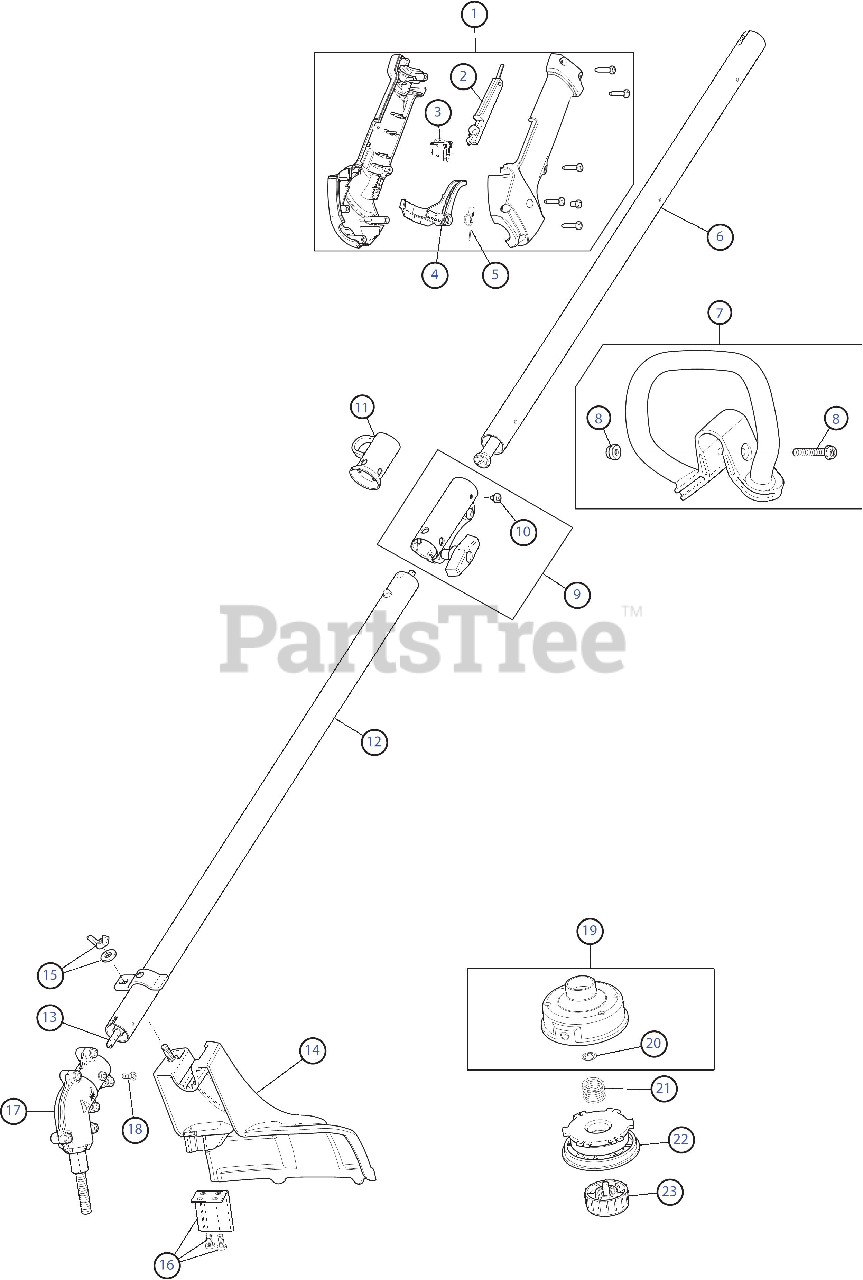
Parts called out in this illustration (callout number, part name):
1	Throttle Housing Assembly
2	Throttle Trigger Lock-Out
3	Trigger Switch Assembly
4	Throttle Trigger
5	Throttle Trigger Spring
6	Upper Drive Shaft Housing Assembly
7	D-Handle
8	D-Handle Hardware Assembly
9	Split Boom Coupler
10	Anti-Rotation Screw
11	Hanger
12	Lower Drive Shaft Housing Assembly
13	Lower Flexible Drive Shaft
14	Shield Assembly
15	Shield Mounting Hardware
16	Blade Assembly
17	Gear Box Assembly
18	Anti-Rotation Screw
19	Outer Spool Assembly
20	Retainer
22	Inner Reel
23	Bump Knob Assembly
